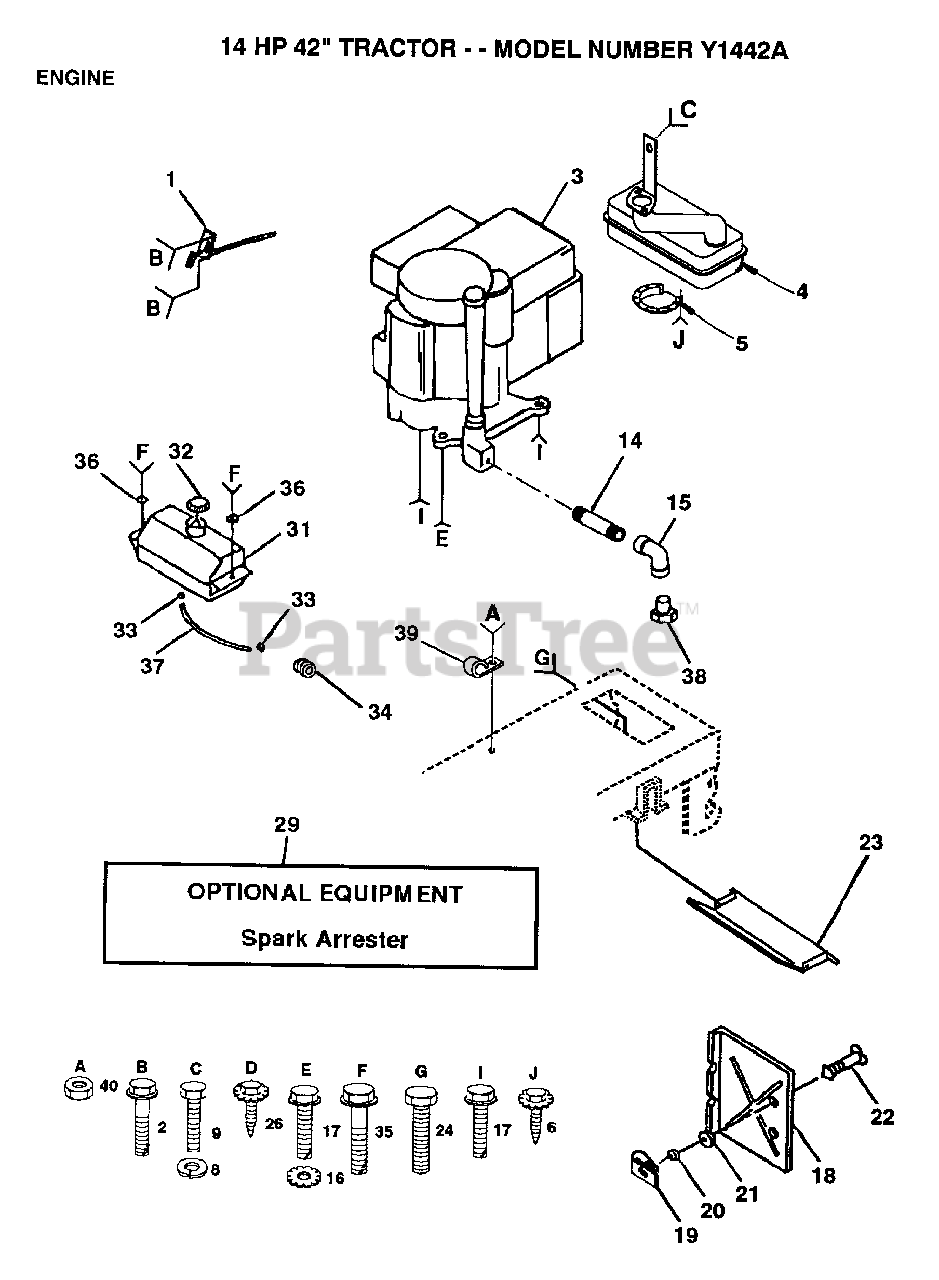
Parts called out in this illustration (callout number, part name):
1	"CONTROL,THROTTL"
2	SCREW LT
3	ENGINE KOHLER
4	MUFFLER
5	DEFLECTOR.222573
8	LOCKWASHER
9	BOLT
14	PIPE NIPPLE LT
15	ELBOW
16	LOCKWASHER
17	SCREW
19	RECEPTACLE LT
20	RETAINER LT
21	WASHER
22	STUD.1/4.TURN
24	SCREW
29	SPARK ARREST KIT
31	TANK.FUEL.LT.
33	HOSE CLAMP
35	SCREW HEX CRT
36	WASHER
39	CLIP T
